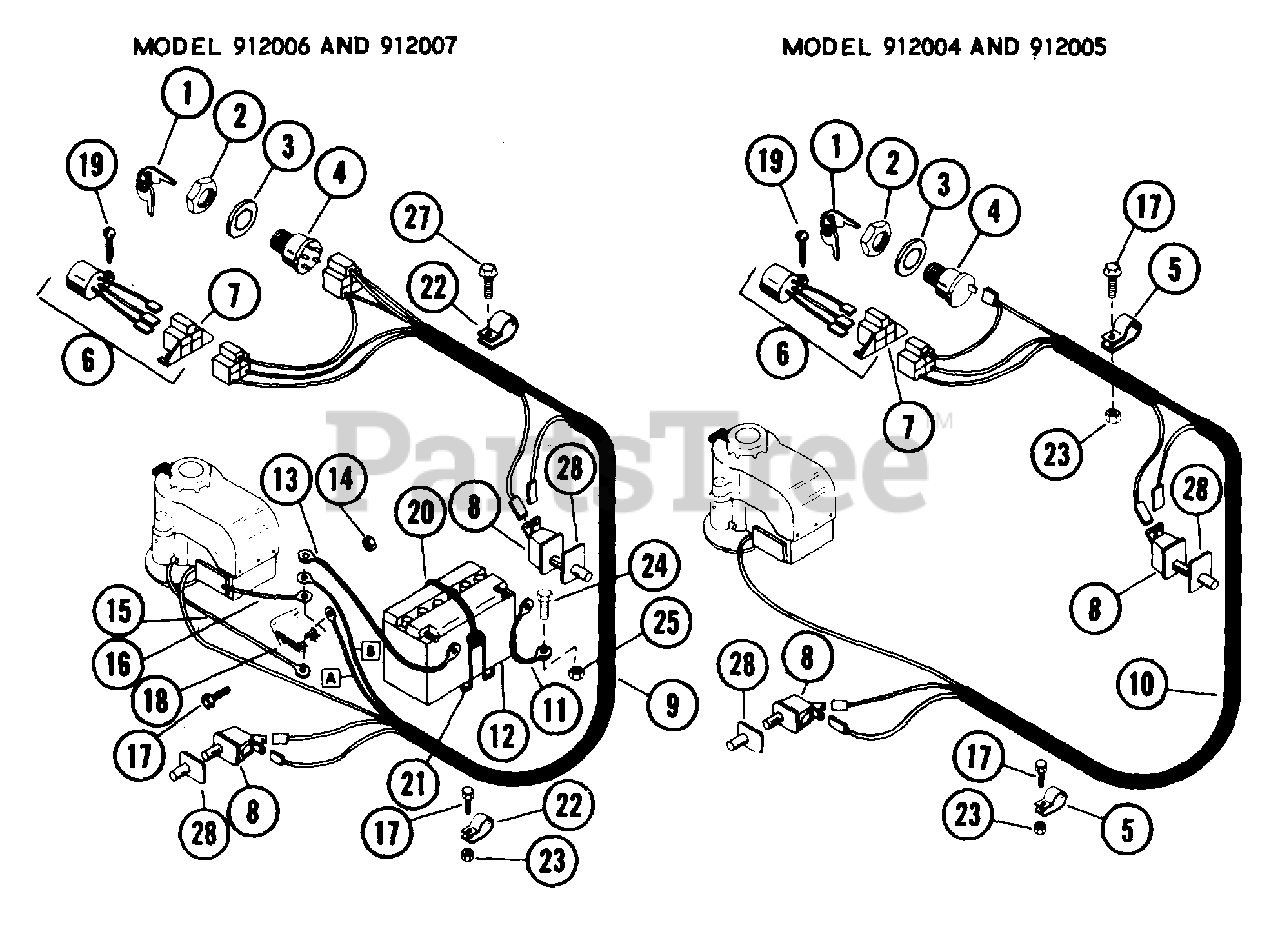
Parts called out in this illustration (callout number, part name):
1	KEYS
2	NUT .625-32 ALUM
3	WSHR-LK-INT .625X.045 PL
4	IGNITION SWITCH ASSEMBLY
4	KEY SWITCH ASSEMBLY
5	CLIP
6	MODULE ASSEMBLY
7	CONNECTOR
9	WIRE HARNESS
10	WIRE HARNESS
11	GROUND CABLE
12	BATTERY
13	BATTERY CABLE
14	NUT-LK-CTR .250-20 PL
15	GROUND CABLE
16	CHARGING WIRE
17	BLT-HEX .25-20X.50 PL GR2
18	SOLENOID
19	SCR-TAP 10-12X.50 CRPH PL A
20	BATTERY STRAP
21	HOOK
22	CLIP
23	NUT-LK-CTR .250-20 PL
24	BLT-HEX .25-20X.63 PL GR2
25	NUT-LK-FLG .250-20 PL
26	BLT-HEX .25-20X.50 PL GR2
27	BLT-SERHFWH .31-18X.50 PL
28	SWITCH BOOT
